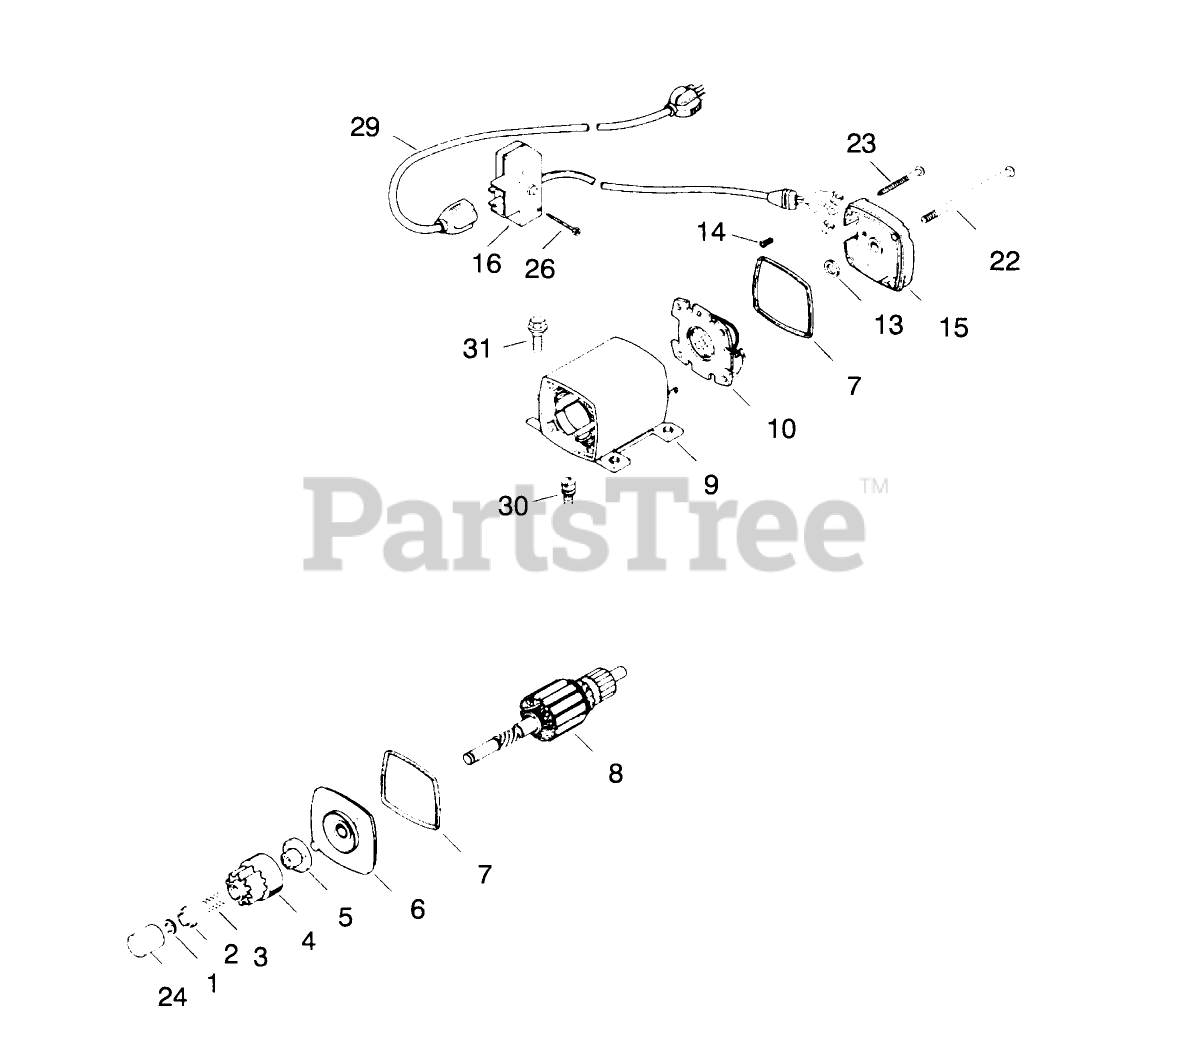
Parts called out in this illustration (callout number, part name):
1	Ring-Retainer
2	Retainer-Spring
3	Spring-Anti Drift
4	Gear
5	Nut-Engaging
6	Cap Assembly-Cap End (Incl. Ref. #7)
7	O-Ring
8	Armature
9	Housing Assy.
10	Card ASM
13	Washer-Thrust
14	Screw-Ground
15	Cap Assembly Commutator End (Incl. Ref. #7)
16	Switch Box ASM
22	Bolt-Case
23	Screw-Ground
24	Cover-Dust
26	Screw
29	Cord-Extension
30	Screw
31	Screw (1/4-20x1/2)
